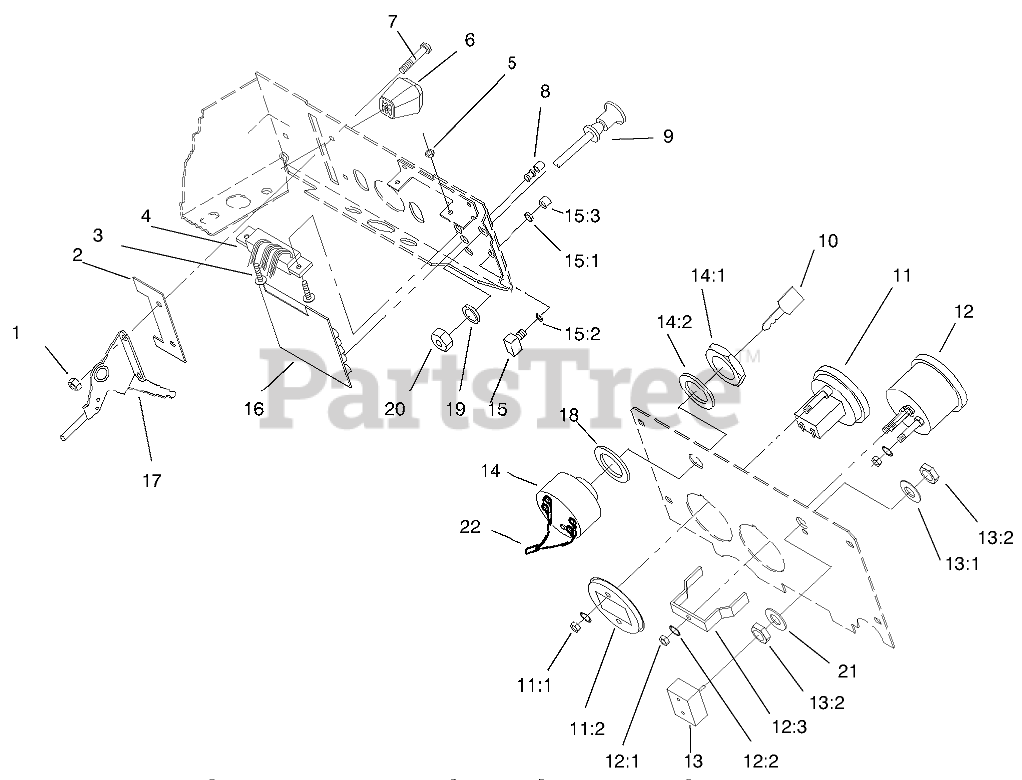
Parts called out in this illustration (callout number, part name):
1	Nut
2	STOP-THROTTLE
3	Screw
4	P.C. BOARD HARNESS
5	NUT-HEX
7	SCRW-PHC
8	ASSY LENS & BUSHING
9	CONTROL-CHOKE
10	KEY-IGNITION
11	Hourmeter
11:1	NUT-HEX, KEPS
11:2	Retainer
12	VOLTMETER
12:1	NUT-HEX
12:2	WASHER-LOCK
12:3	CLAMP-MOUNTING
13	SWITCH-LIGHTS
13	TAB-WASHER
14	IGNITION SWITCH ASM
14:2	WASHER-LOCK
15	SWITCH-PUSH BUTTON
15:1	NUT F/W 116796
15:2	Washer
15:3	BUTTON F/W 116796
16	Board-Pc
17	CONTROL-THROTTLE
18	WASHER
19	WASHER-FLAT
20	NUT-HEX PALNUT
21	WASHER
